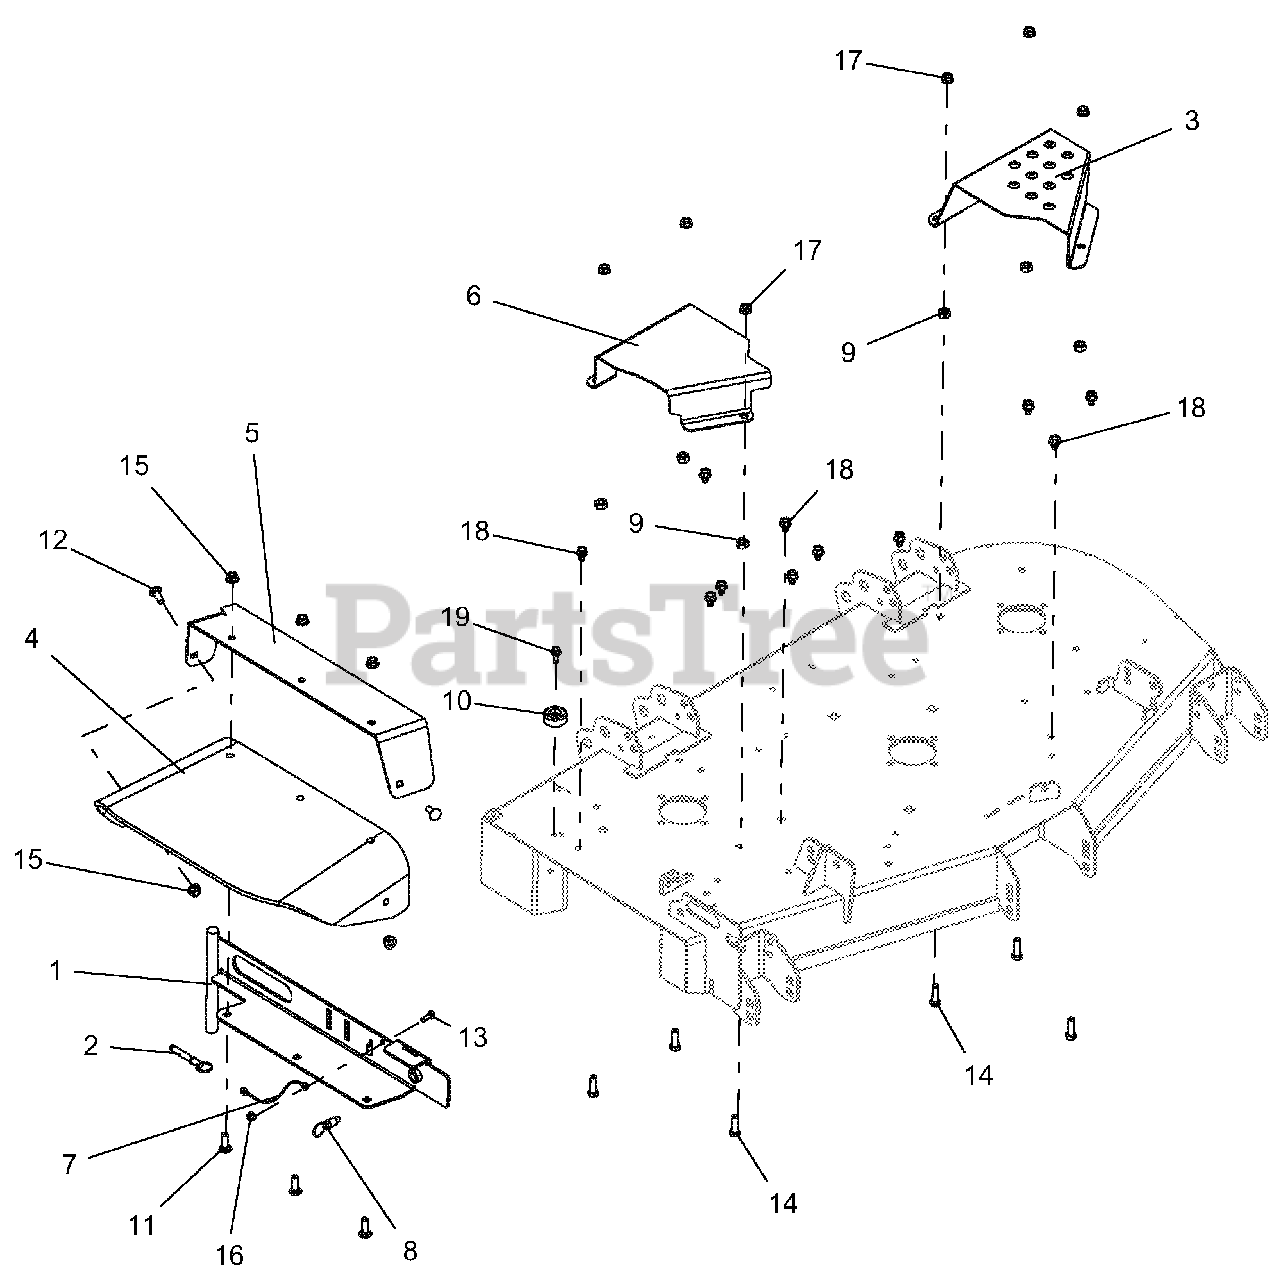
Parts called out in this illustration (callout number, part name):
1	WLDMT, 44"-48" DISCH CHUTE MTG-RED
2	PIN, SPRING BALL .375 OD X 1.50
3	GUARD, 44-52" LH DECK BELT-BLACK
4	CHUTE, RUBBER DISCHARGE
5	KIT, PT DISCH CHUTE SUPT W/SAFETY DECALS-RED
6	GUARD, 48"-52" RH DECK BELT-BLACK
7	CABLE, 6.0 LANYARD, NYLON
8	PULL PIN,.50-13THDX.310 PLNGR
9	NUT-HEAVY HEX .38-16 YWZC
10	BUMPER, RECESSED 1.50 X .63 W/.31 HOLE
11	BLT-RDHDSQNK .38-16X1.25 G5 YWZC
12	BLT-RDHDSQNK .38-16X1.00 G5 YWZC
13	BLT-HEX .25-20X.75 GR5 YWZC
14	BLT-HEX .38-16X1.25 GR5 YWZC
15	NUT-LK-NYL-FLG .38-16 YWZC
16	NUT, LK-TOP-FLG .25-20 YWZC
17	@NUT-SPNLK-FLG .375-16 YWZC
18	SCR-TAP .38-16X.50 HWH TR YWZ
19	SCR-TAP .31-18X.75 HWH TR YWZ
